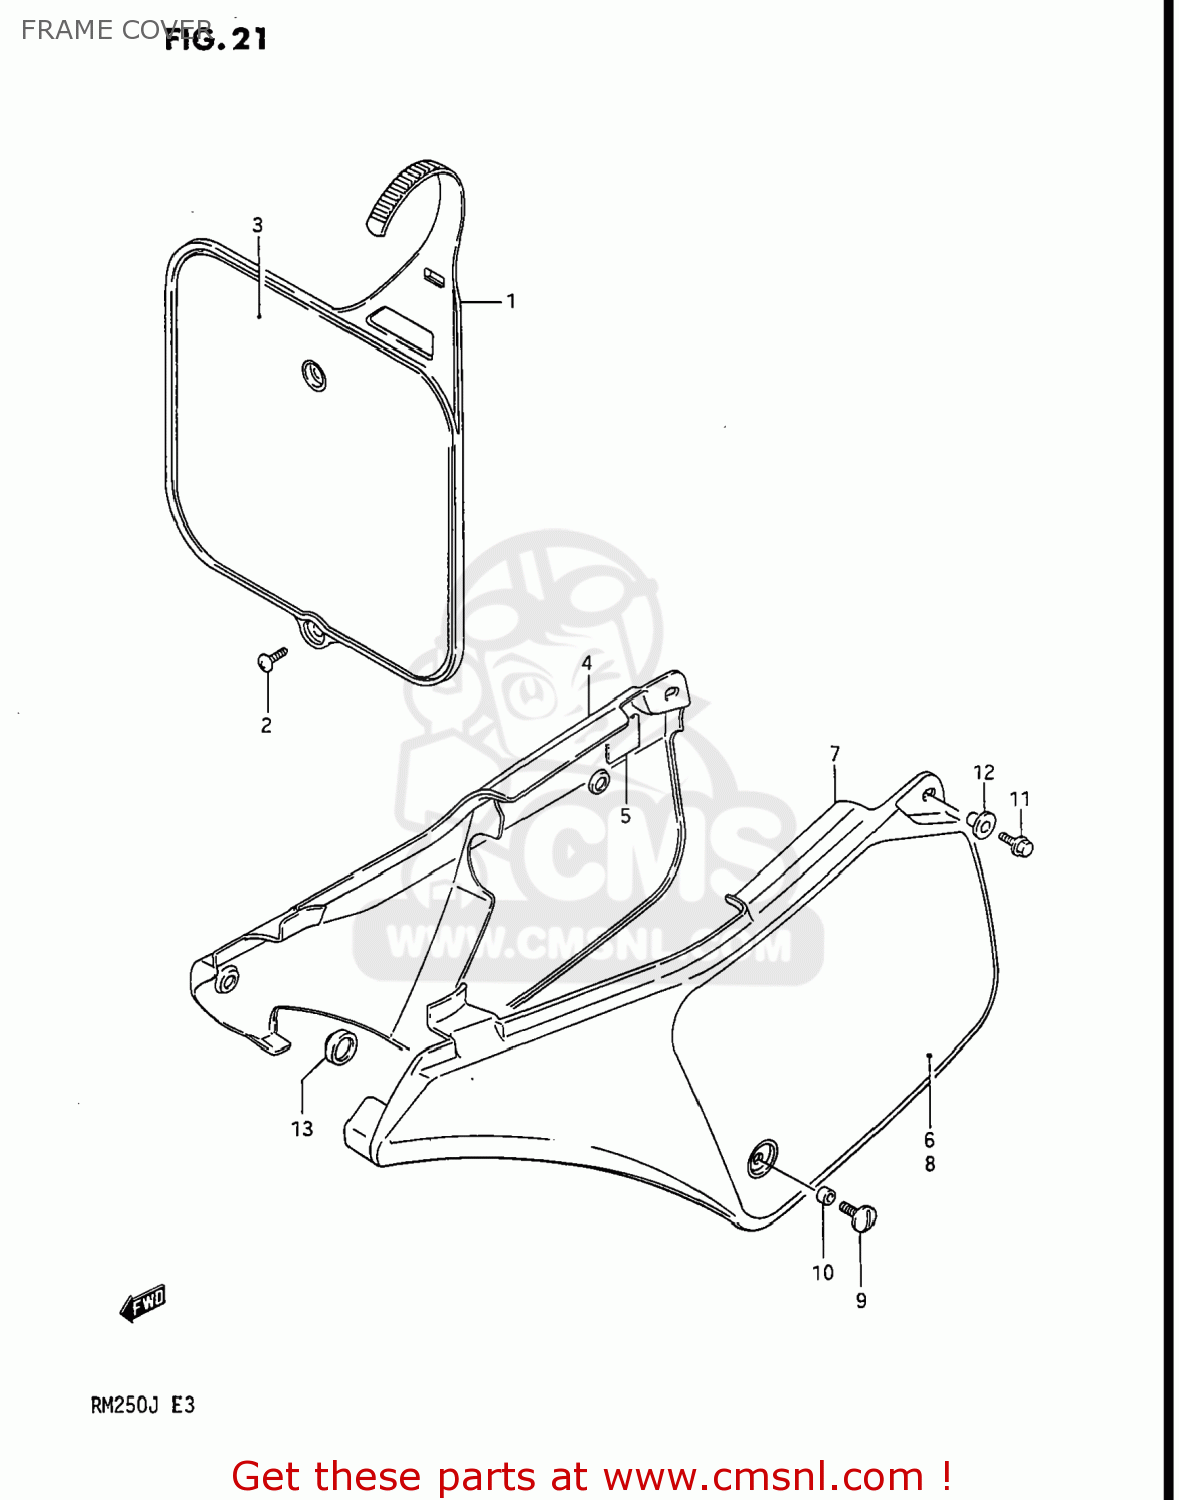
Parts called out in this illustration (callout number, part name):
1	PLATE,NUMBER,FRONT
2	SCREW
3	EMBLEM,FRONT NUMBER PLATE
4	COVER,FRAME,R(YELLOW)
5	SHIELD,FRAME COVER,RIGHT
6	EMBLEM
7	COVER,FRAME,L(YELLOW)
8	EMBLEM,FRAME COVER,LEFT
9	SCREW(6X14)
10	SPACER (6.1X8X3.5)
11	BOLT
12	WASHER
13	CUSHION
